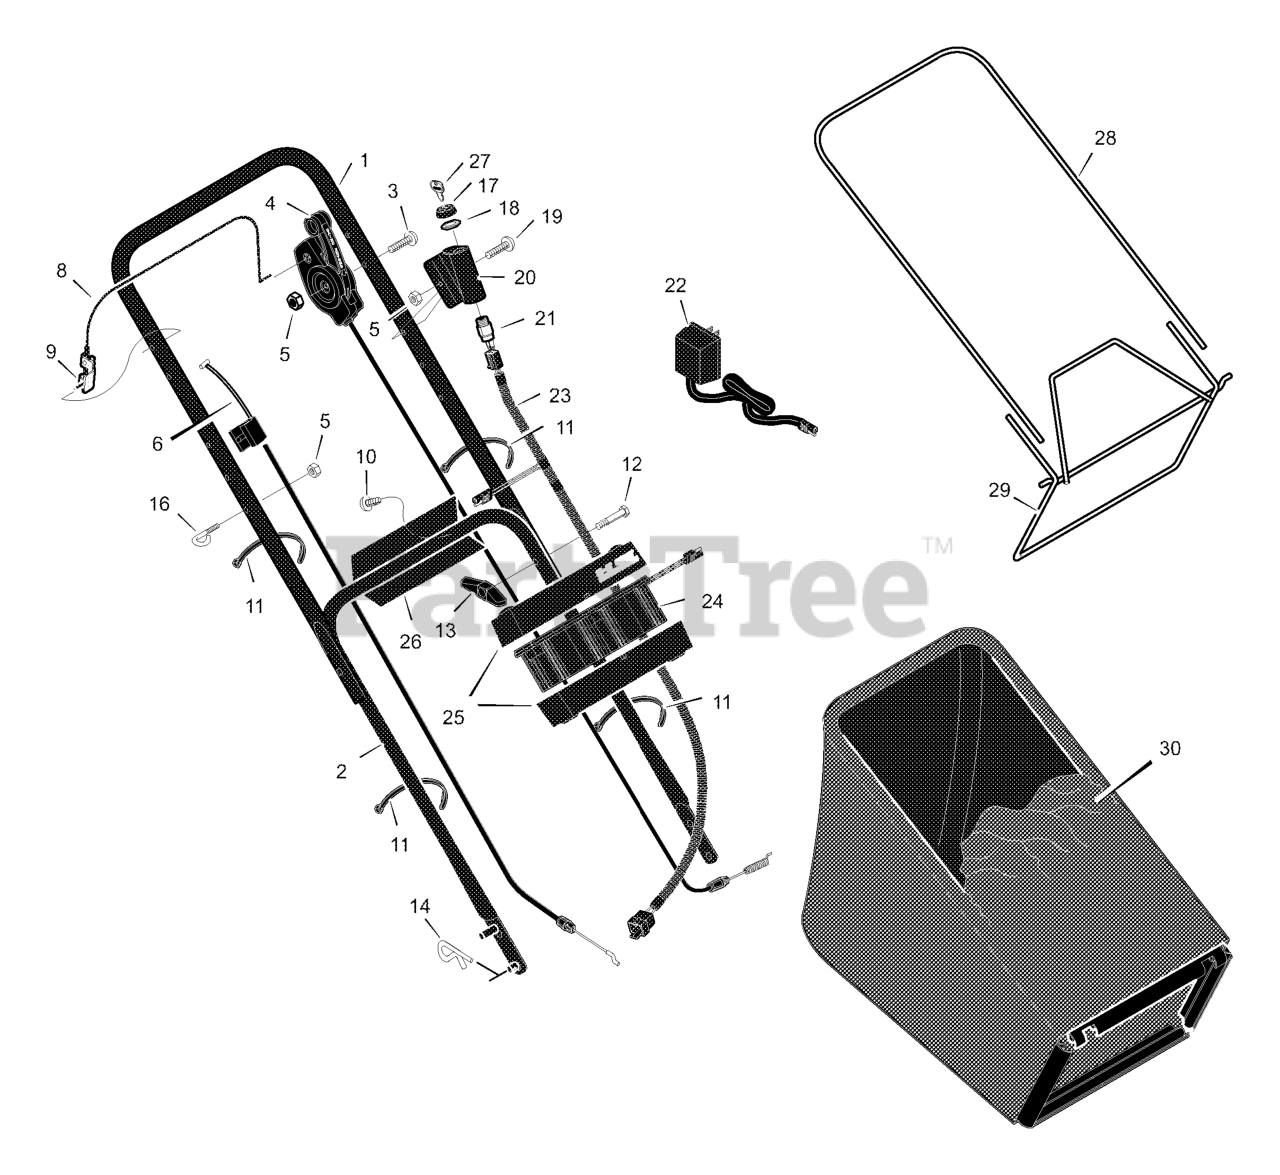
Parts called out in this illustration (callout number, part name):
1	Handle, Upper (Gray)
2	Handle, Lower (Gray)
4	Control, Drive
5	Locknut
6	Cable, Stop
8	Engine Stop Lever
9	Bracket, Stop Lever
11	Fastener, Cable
13	Knob
14	Pin, Hair
16	Guide, Rope
17	Cap
18	Nut
20	Cover, Ignition
21	Switch Ignition & Key
22	Charger, Battery
23	Harness, Wiring
24	Battery
25	Case, Battery
26	Bracket, Battery
27	Key, Ignition
28	Frame, Top
29	Frame Assembly
30	Bag, Cloth
